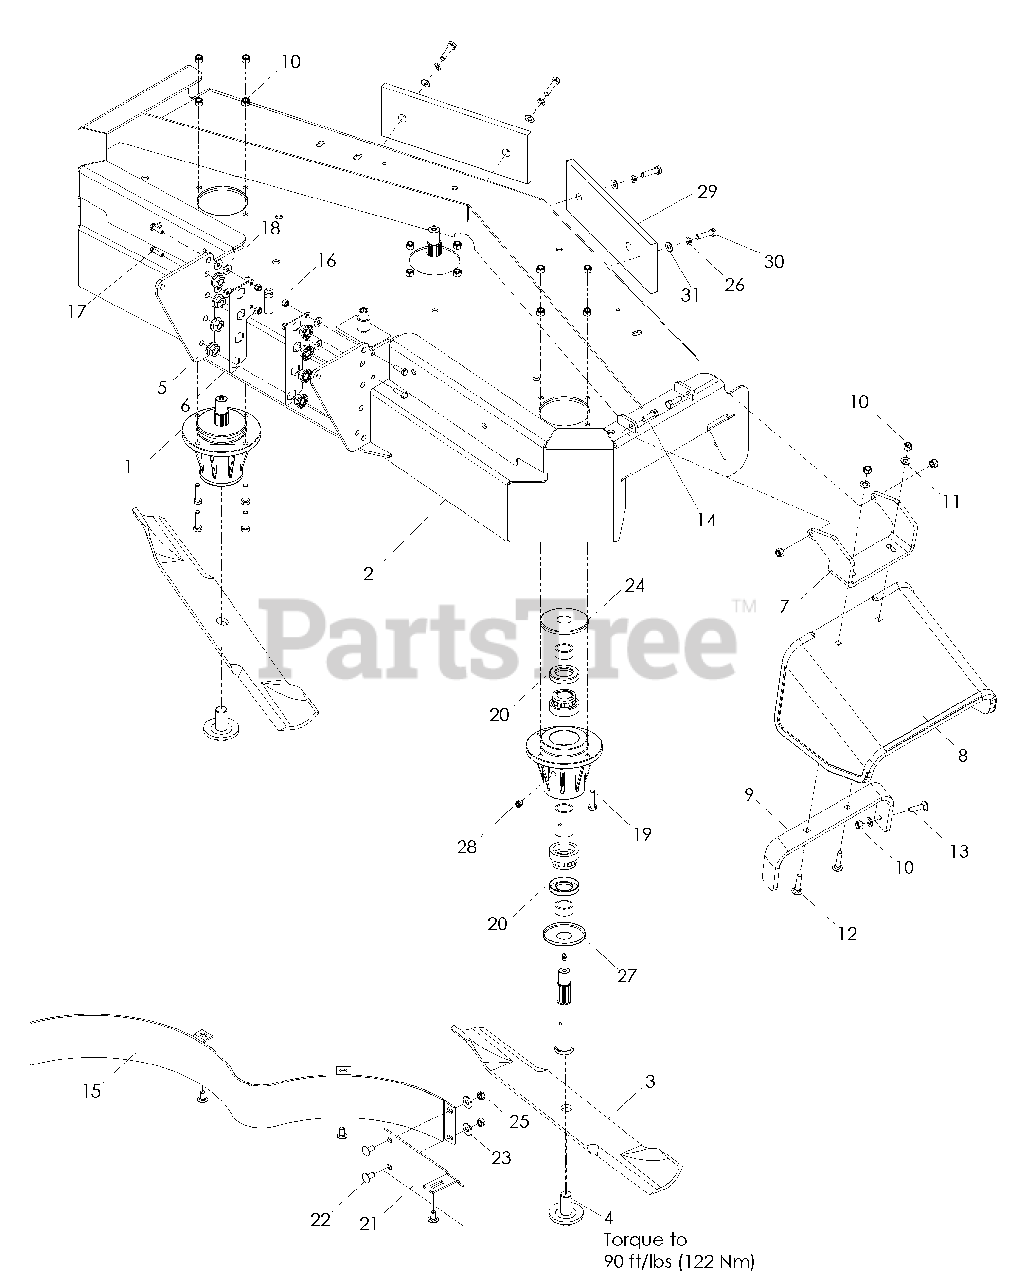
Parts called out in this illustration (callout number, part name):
1	SPINDLE ASSEM
2	DECK W DECALS, 52"
4	BOLT, BLADE
5	NUT, FLANGE, 1/2-13
6	NUT, PLATE
7	HINGE, CHUTE
8	RUBBER CHUTE
9	REINFORCEMENT, BRKT
10	NUT 5/16-18 HEX NYLOC
11	WASHER 5/16 SAE FLAT
12	RHSNB 5/16-18 x 1 1/2
13	RHSNB 5/16-18 x 1 1/4
14	HCS 5/16-18 x 1
15	MAIN BAFFLE
16	NUT 1/4-20 HEX NYLOC
17	HCS 1/4-20 x 7/8
18	WASHER 1/4 FLAT
19	HCS 5/16-18 x 1 1/4
20	SEAL, SHAFT
21	CENTER BAFFLE
22	RHSNB 5/16-18 x 5/8
23	WASHER 5/16 STD FLT
24	DUST CAP, TOP
25	NUT 5/16-18 HEX CTRLK
26	WASHER 1/2 SLW
27	DUST CAP, BOTTOM
29	WEIGHT, COUNTER
30	HCS 1/2-13 x 1 1/2
31	WASHER 1/2 SAE FLAT
